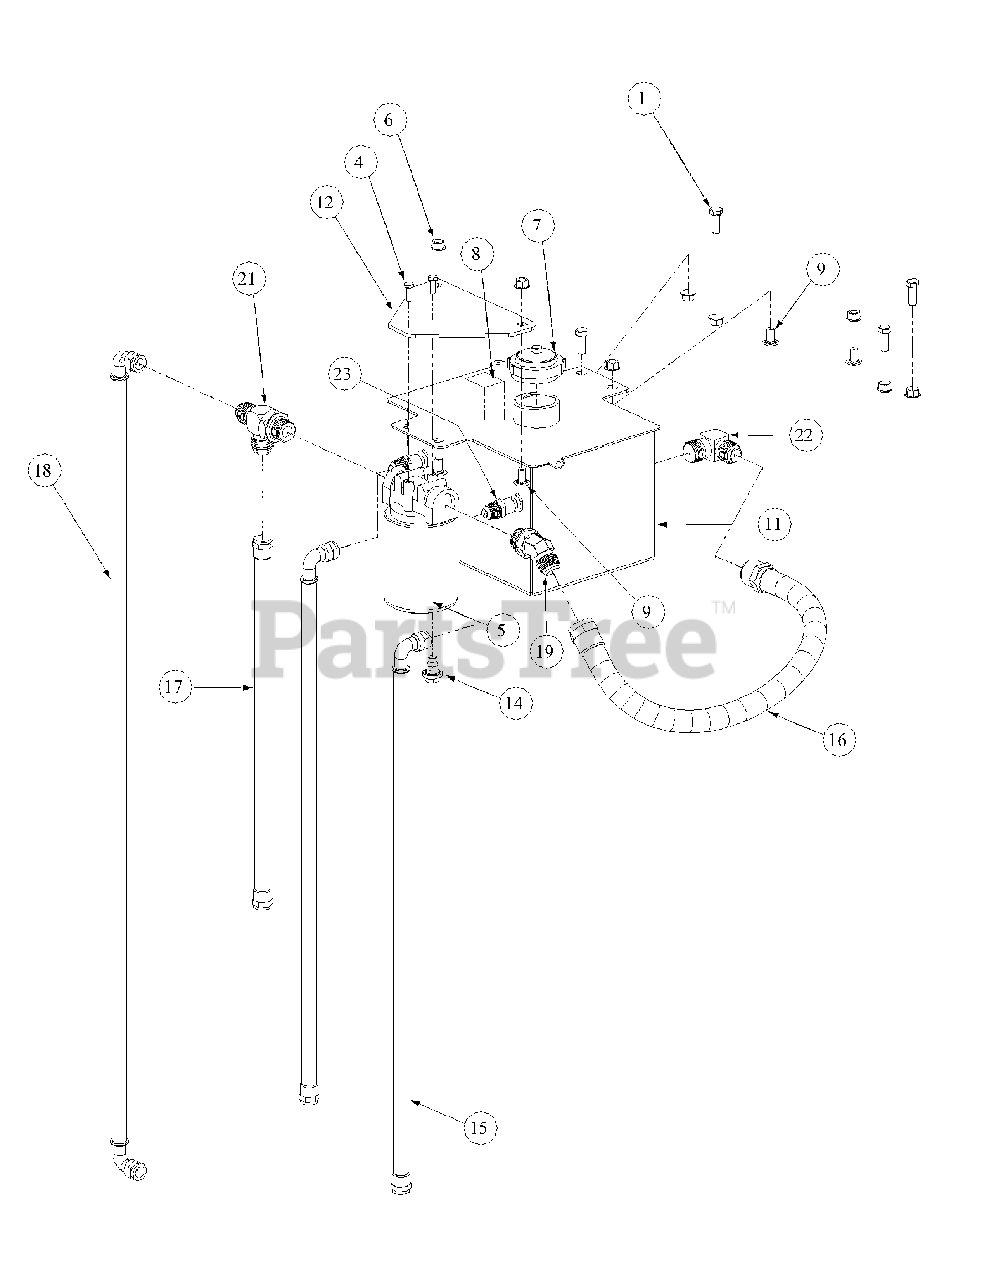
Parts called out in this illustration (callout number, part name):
1	Hex Cap Screw, 3/8-16, 1
3	Protective Hose Cover
4	Hex Cap Screw, 1/4-20, .75
5	Filter Head 3/4
5	33 Micron Filter
6	Hex Nut Flange Lock, 3/8-16
7	Cap, Hydro Oil Tank
8	Decal Oil Only 20W50
9	Carriage Bolt, 3/8-16 x .75 LG.
11	Hydraulic Tank Assembly
12	Mounting Plate Oil Filter
14	Oil Pan Drain w/ Seal and Plug
15	Gearbox to Tank Hose Assembly
16	Tank to Filter Hose Assembly
17	Filter to Left Hand Pump Hose Assembly
18	Filter to Right Hand Pump Hose Assembly
19	Fitting, 45°.
21	Fitting Tee, 3/4 x 1/2 x 1/2
22	Fitting Elbow, 1/2 x 1/2
23	Fitting, 3/8 NPT, 1/2 Flare
